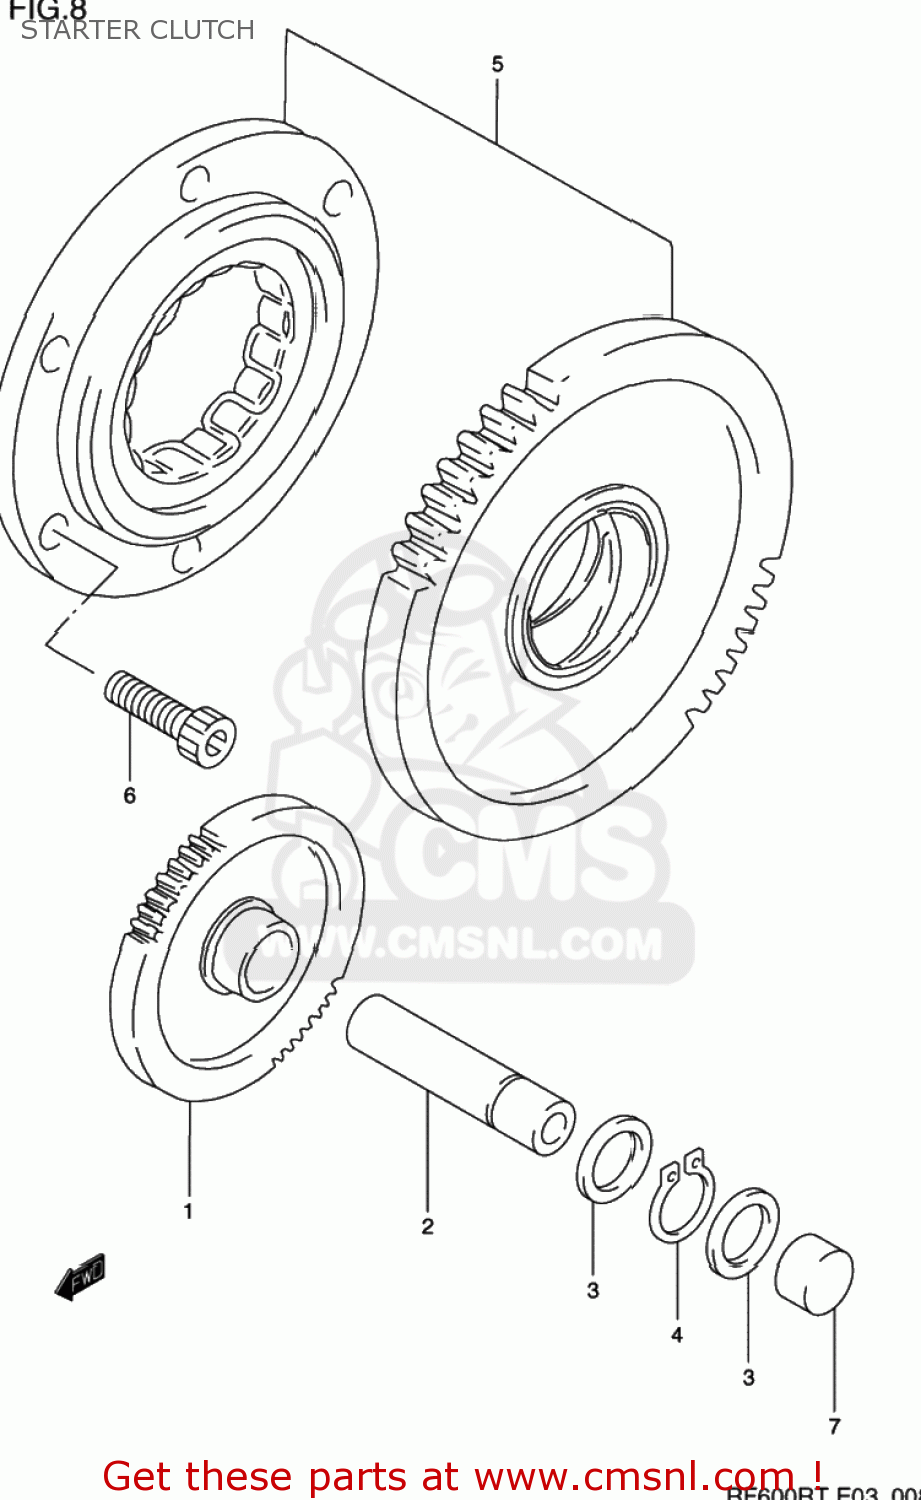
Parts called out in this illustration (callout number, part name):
1	GEAR,STARTER IDLE (NT:1
2	SHAFT,STARTER IDLE GEAR
3	WASHER
4	CIRCLIP,12 MM
5	CLUTCH SET,STARTER
6	BOLT,STRANGER
7	PLUG
